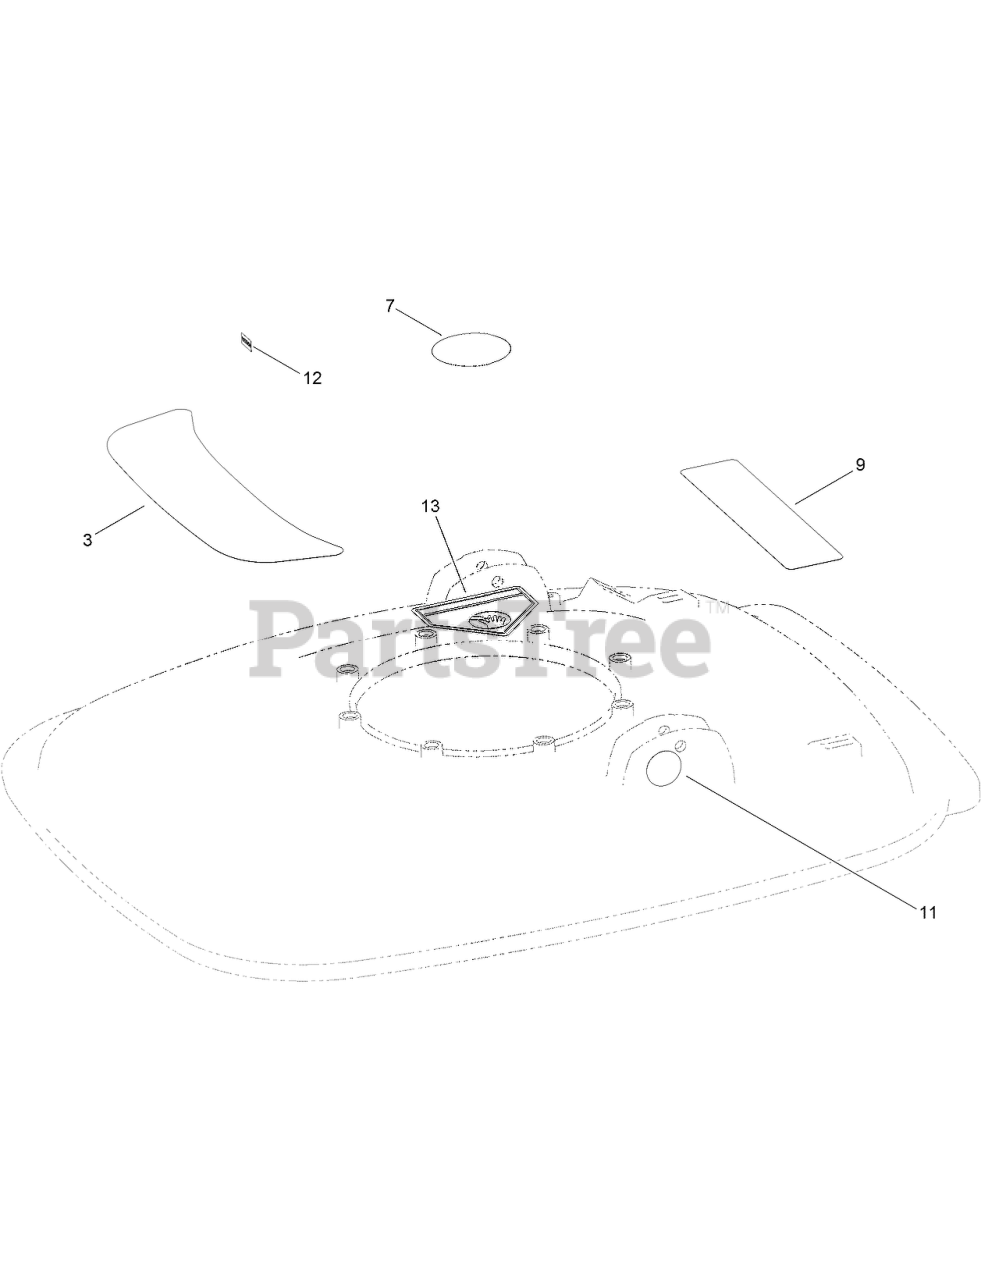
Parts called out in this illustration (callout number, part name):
3	DECAL-HOVER PRO, 500 SERIES
7	DECAL-ENGINE
9	DECAL-WARNING
11	DECAL
12	DECAL-STOP
13	DECAL-DANGER
